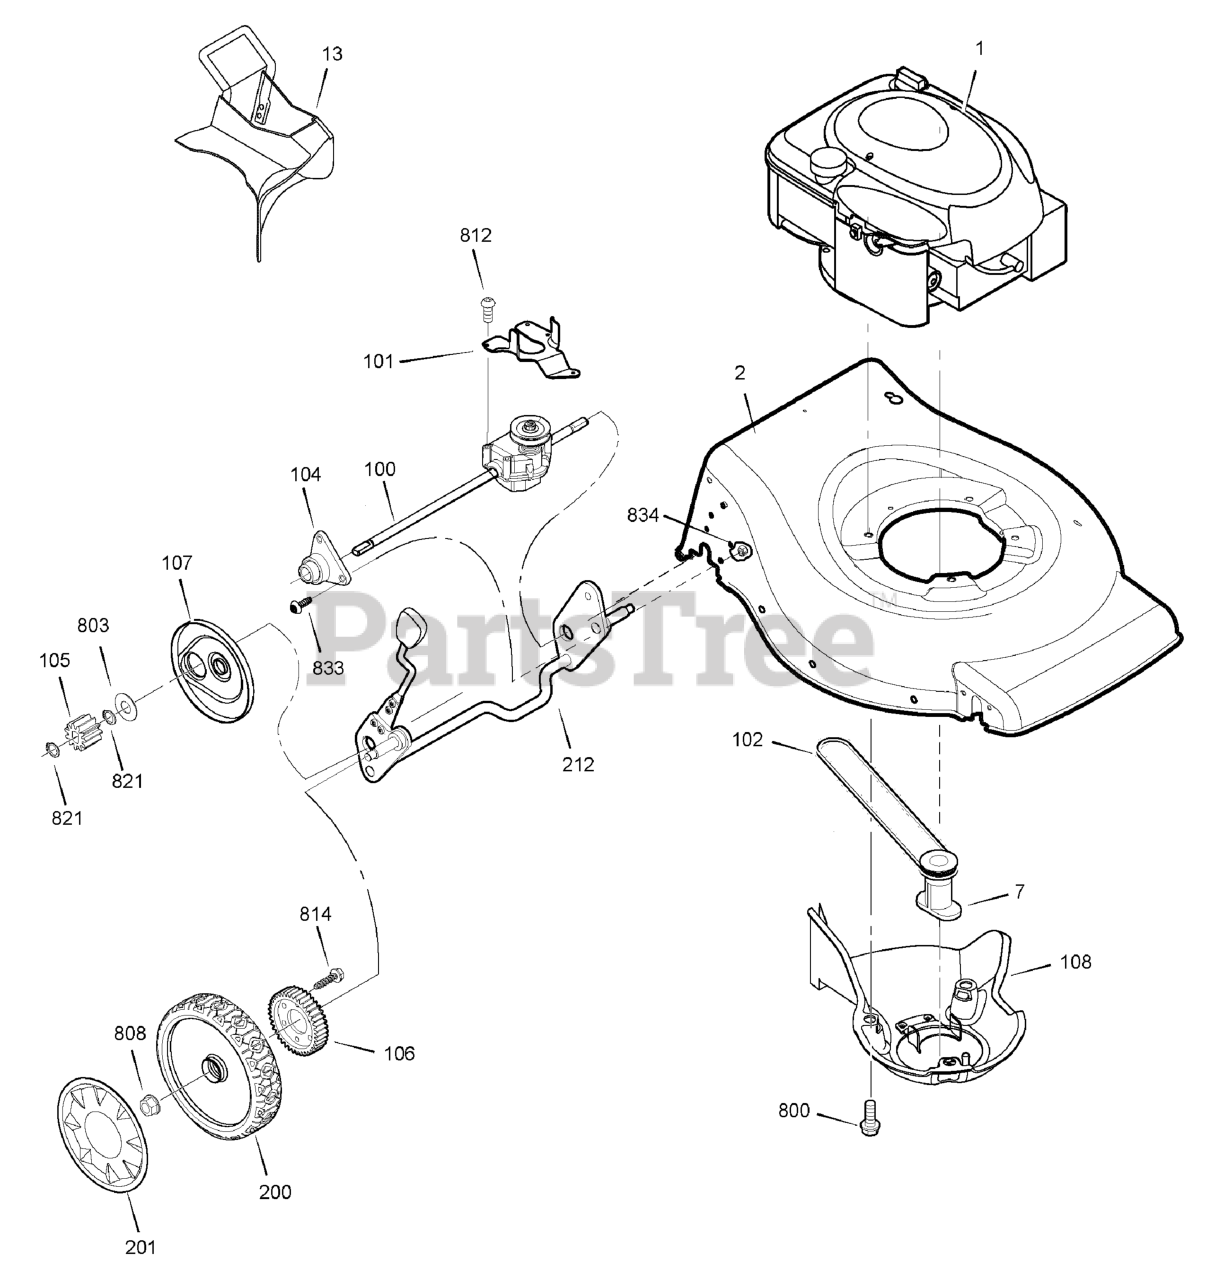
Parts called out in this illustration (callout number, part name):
1	* ENGINE
2	MOWER HOUSING
7	BLADE ADAPTER ASSEMBLY
13	MULCH PLUG
100	TRANSMISSION
101	BELT GUIDE, Transmission
102	V-BELT
104	SLEEVE ASSEMBLY, Rear Axle
105	GEAR, Pinion
106	GEAR, Drive
107	DUST COVER
108	BELT COVER ASSEMBLY
200	WHEEL, Rear
201	HUBCAP, Rear
212	CROSSBAR ASSEMBLY, Rear
800	SCREW, Hex Head, 3/8-16 x 1
803	WASHER, Thrust
808	NUT, Flange, 3/8-16
812	SCREW, #10 x 1
814	SCREW, 1/4-15 x 3/4
821	RING, External Retaining
833	SCREW, Torx, 1/4-20 x 5/8
834	NUT, Flange Lock, 1/4-20
